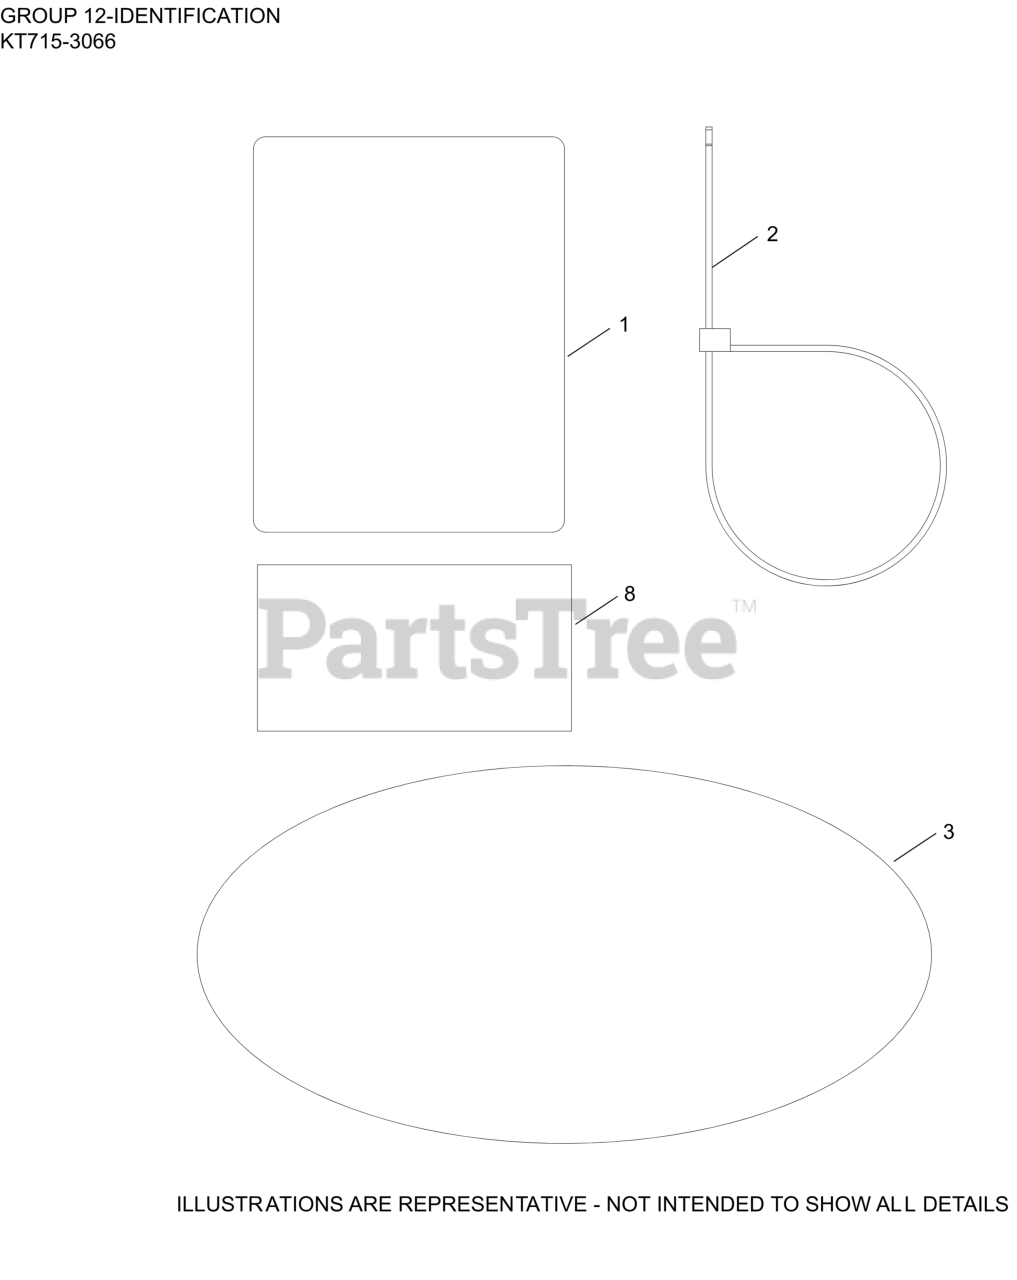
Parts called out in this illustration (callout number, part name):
1	LABEL, CLEAR LAMINATION
3	LABEL, 7000 SERIES (20HP, PRO)
8	DECAL, USA
